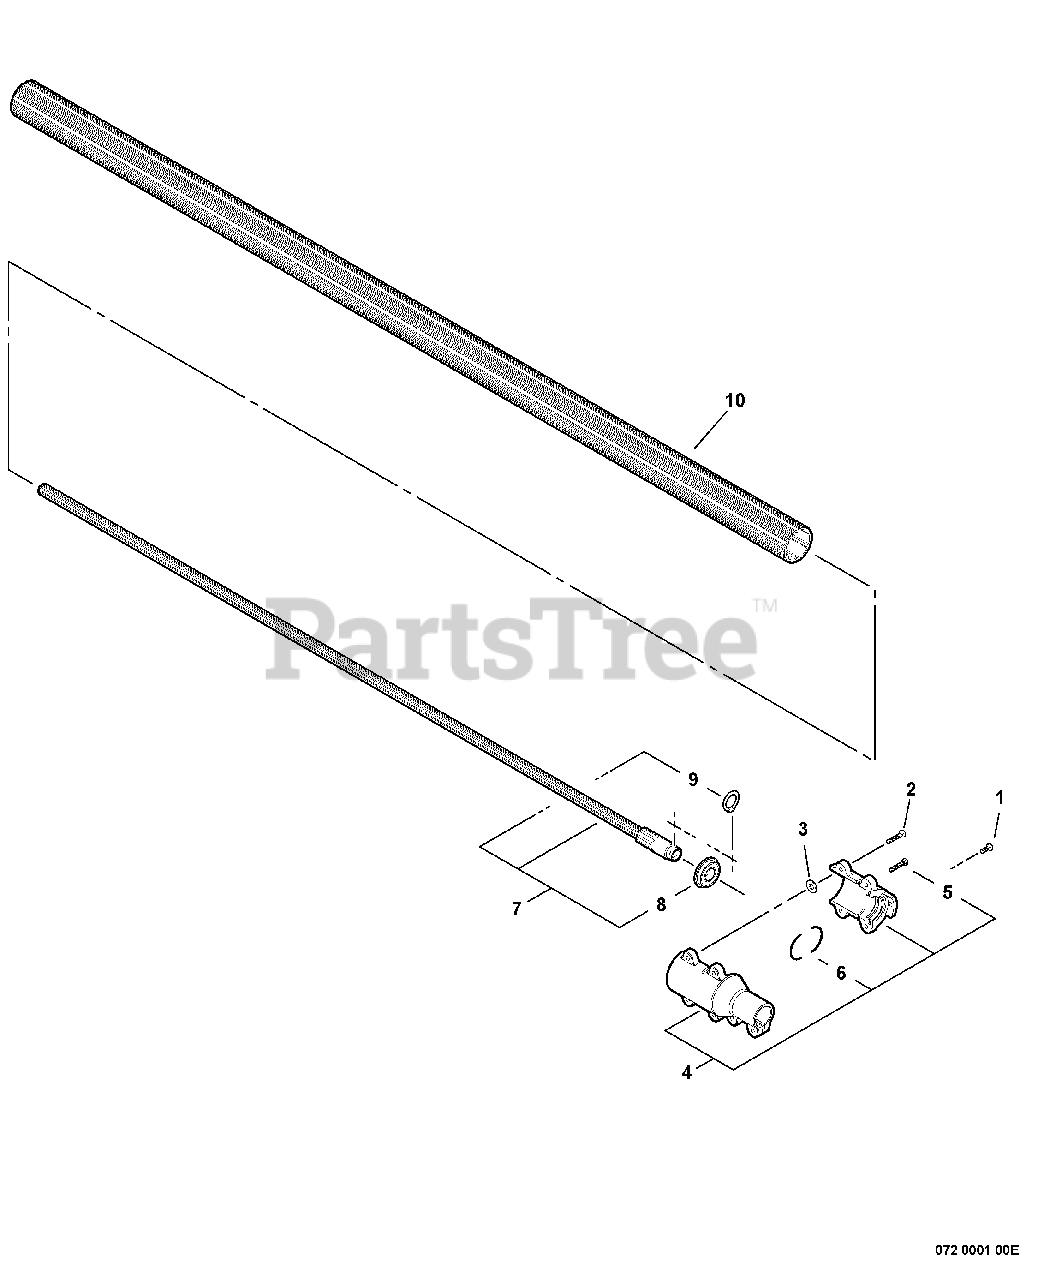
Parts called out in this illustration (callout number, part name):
1	BOLT 5×14
2	BOLT 5×20
3	WASHER 5
4	COUPLING ASSY
5	BOLT, TORX 5×20
6	CUSHION
7	DRIVESHAFT ASSY, LOWER
8	BEARING, BALL 15×32×9
9	RING, RETAINING
10	PIPE, MAIN - ORANGE
